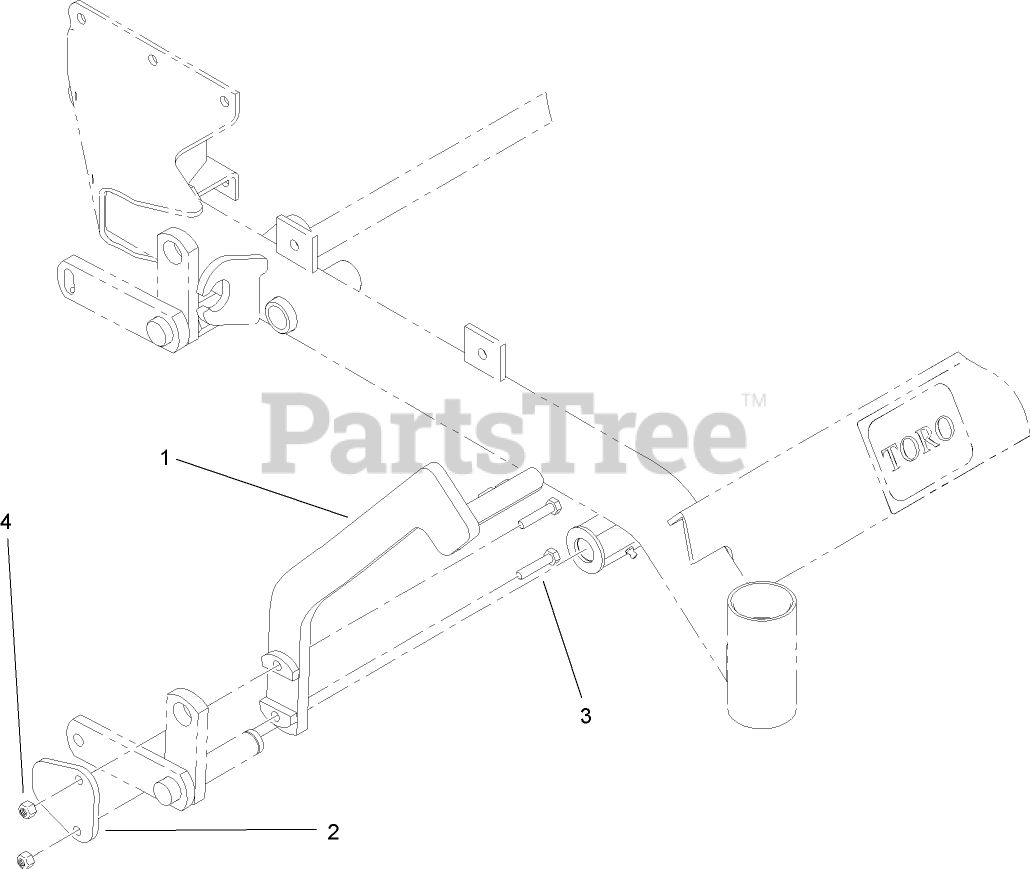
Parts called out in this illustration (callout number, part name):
1	DECK LIFT LEVER ASM
3	SCREW-HH
4	NUT-LOCK, NI
